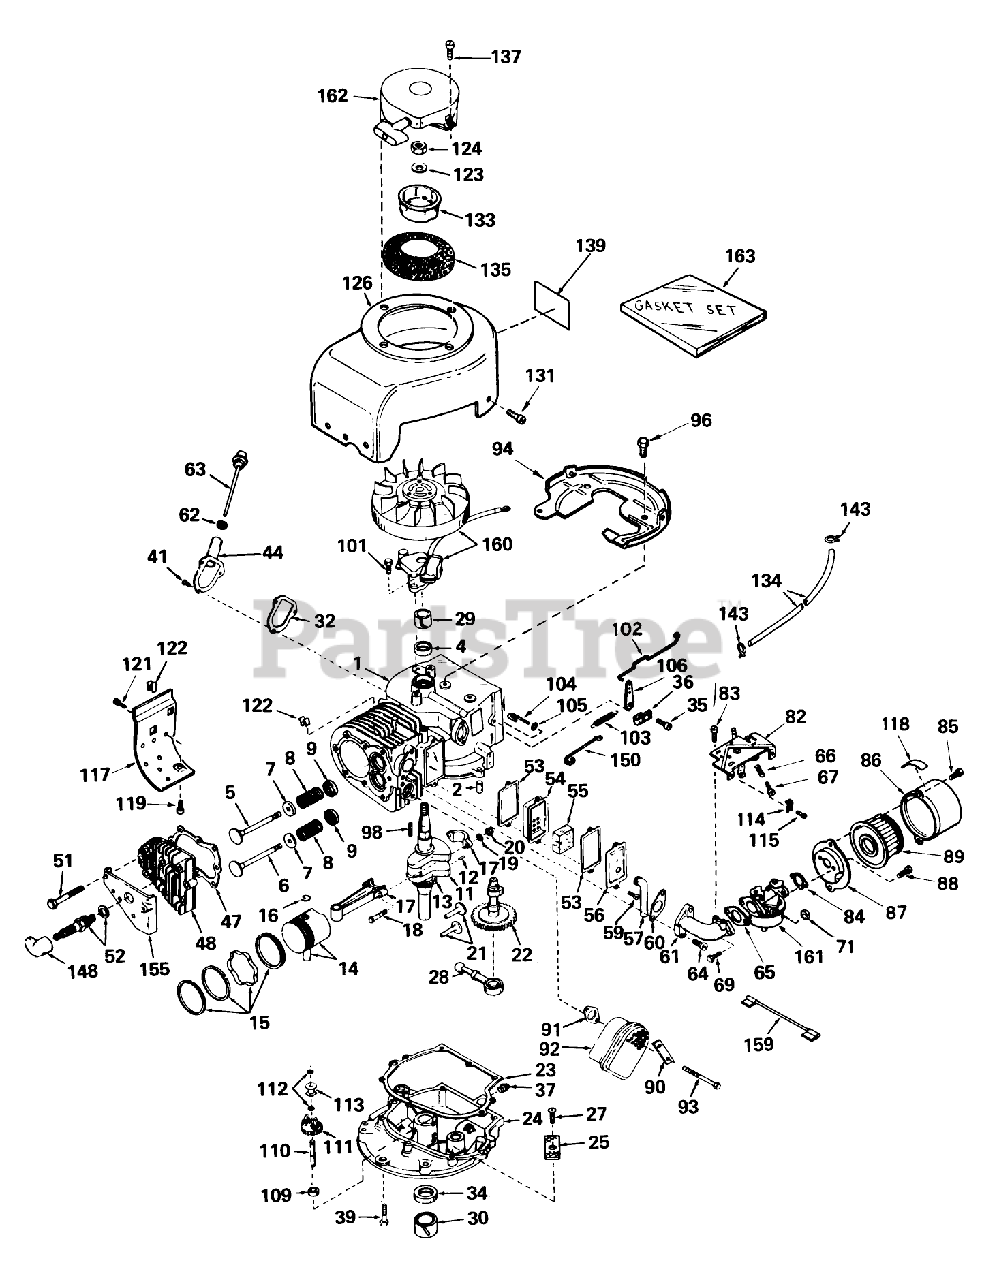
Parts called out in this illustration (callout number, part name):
1	Cylinder Assy.(Incl. Nos. 2 4)
2	Pin-Dowel
4	Seal, Oil
5	Valve, Intake, Standard (Incl. No. 9)
5	Valve, Intake, 1/32" Oversize (Incl. No. 9)
6	Valve, Exhaust, Standard (Incl. No. 9)
6	Valve, Exhaust, 1/32" Oversize (Incl. No. 9)
7	Cap-Spring, Valve
8	Spring-Valve
9	Keeper-Spring, Valve
11	Crankshaft Assy. (Incl. Nos. 12 13)
12	Pin, Groove
13	Gear-Crankshaft
14	Piston Pin Assy., Std., (Incl. 2 of No. 16)
14	Piston Pin Assy., .010 oversize (Incl. 2 of No. 16)
14	Piston Pin Assy., .020 oversize (Incl. 2 of No. 16)
15	Ring Set, Piston (Standard)
15	Bearing-Wrist Pin
15	Bearing-Crankshaft
17	Rod Assy., Connecting (Incl. Nos. 18, 19 20)
18	Bolt, Connecting Rod
19	Washer
21	Lifter Valve
22	Camshaft (Compression Release)
23	Gasket-Cover, Cylinder
24	Flange Assy., Mounting (Incl. #25, 27, 34, 37 110)
25	Screen-Oil Filter
27	Screw
28	Pump, Oil
29	Bushing, Crankshaft
30	Bushing, Crankshaft
32	Gasket, Filler tube
34	Seal-Oil
35	Screw
36	Clamp-Lever, Governor
37	Plug-Drain, Oil (SQH 1/4-18)
39	Screw (1/4-20 x 1-1/4)
41	Screw
44	Tube, Oil Filler
47	Gasket-Head, Cylinder
48	CYLINDER HEAD
51	Screw Hex Hd. Cap
52	Plug, Spark (J17LM or equiv.)
53	Gasket-Breather
54	Body-Breather
55	Element-Breather
56	Cover-Valve
57	Tube-Breather
59	Screw
60	Gasket-Intake
61	Pipe, Intake
62	Gasket
63	Dipstick, Oil (Incl. No. 62)
64	Screw (T-30, 5/16-18x1-3/32)
65	Gasket
66	Spring-Compression
67	Screw
71	Nut and Lock Washer (1/4-28)
82	Control Assy., Speed (Incl. Nos. 161 162)
83	Screw (10-24 x 9/16)
84	Gasket
85	Screw
86	Body
87	Bracket
88	Screw (10-32 x 1/2)
89	Element
90	62513 SNWTHWR W/284
91	Gasket Exhaust
92	Muffler
93	Screw Hex Hd.
94	Baffle Blower Housing
96	Screw (1/4-20x19/32)
98	Key, Flywheel
101	Screw
102	Link Governor
103	Spring Governor
104	Rod, Governor (Incl. Nos. 146)
105	Washer-Flat
106	Lever-Governor
109	Spacer
110	Shaft, Governor
111	Governor Gear ASM
112	Ring-Retaining
113	Spool-Governor
114	Conduit
115	Screw (10-32 x 3/8)
117	Emnsion, Blower Housing
118	Decal
119	Screw
121	Screw
122	51004 GIL ROTARY TI
123	Washer
126	Housing, Blower
131	Screw, Hex Hd.
133	Cup-Starter
134	Line-Fuel
135	Screen, Air
137	Screw
139	480B GIL SNWTHWR O/
143	Clamp-Line, Fuel
148	Cover-Spark Plug
150	Link Governor Spring
155	Cover-Head, Cylinder
159	Wire, Ground
160	Magneto
161	Carburetor
162	Starter, Rewind
163	Gasket Set (Incl. items marked*)
